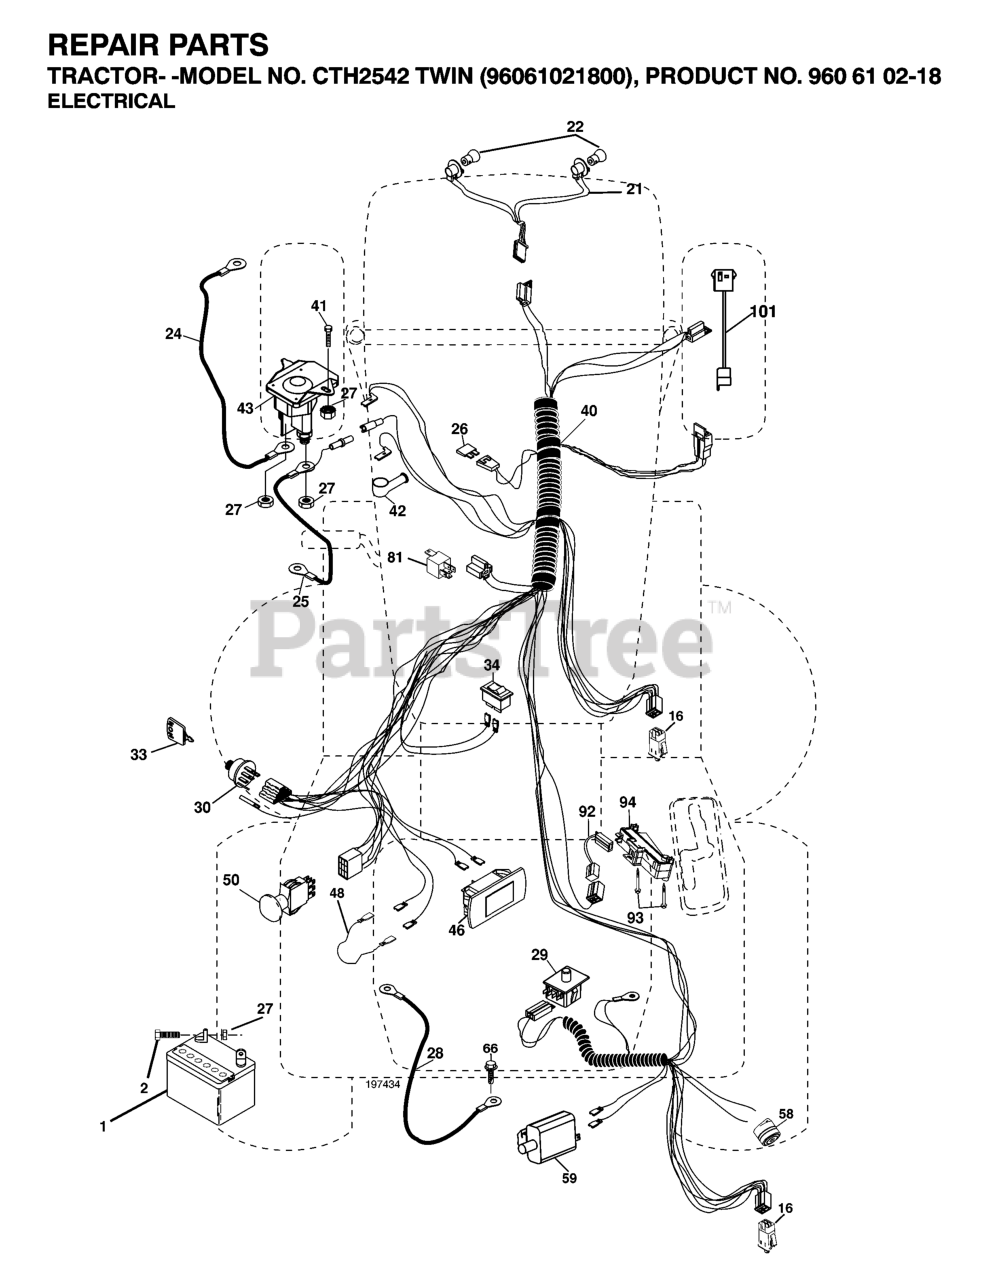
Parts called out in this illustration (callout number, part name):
1	BATTERY 12V .35 AMP
2	BOLT.HEX.1/4.X.3/4.DICHROMATE
16	SWITCH INTERLOOK PUSH-IN
21	HARNESS ASSY LIGHT
24	CABLE.BATTERY.6GA.16"RED
25	CABLE BATTERY
26	FUSE 20AMP
27	NUT
28	CABLE GROUND
29	SWITCH.SEAT.DP W/RAMPS
30	SWITCH.IGN.DELTA.W.LGH.ROS
33	KEY MLD GEN DELTA
40	RP HARNESS.IGN.ELECT.REG.CRD
41	BOLT
42	TERMINAL COVER
43	SOLENOID.W/BRASS.PLUNGER
46	RP.GUAGE.SRVCMNDR.HRMTR.
48	RP.GUAGE.SRVCMNDR.HRMTR.
50	RP.PTO.SWITCH.8 TERMINAL.BLACK
58	BUZZER
59	.WITCH.FULL BAGGER.INDICATOR
81	RELAY.ASSY.T
92	HARNESS.PIGTAIL.CONSLE
93	SCREW.PLASTITE
94	MODULE.REVERSE.ROS
101	PIGTAIL.MATNLK.NEW.HAR
